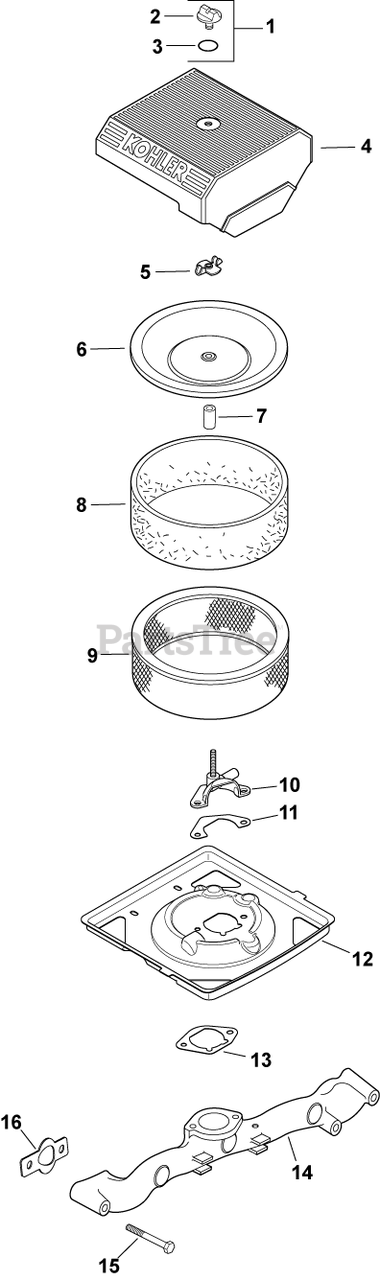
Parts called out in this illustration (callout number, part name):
1	KIT, KNOB W/SEAL
2	KNOB, COVER
4	COVER, AIR CLEANER
5	NUT, WING
6	COVER, INNER AIR CLEANER
7	SEAL, INNER AIR CLEANER
8	ELEMENT, PRECLEANER (LOW)
9	ELEMENT, AIR CLEANER - Also available Retail Packaged 47 883 03-S1 Air Filter Kit
10	CUP, SPITBACK W/STUD-USE 24 109 26-S
11	GASKET, FUEL SPITBACK CUP
12	BASE, AIR CLEANER-USE 24 094 86-S
13	GASKET, AIR CLEANER BASE
14	MANIFOLD, INTAKE
15	SCREW, FLG M6X1.0X55
16	GASKET, INTAKE MANIFOLD USE 24 041 79-S
